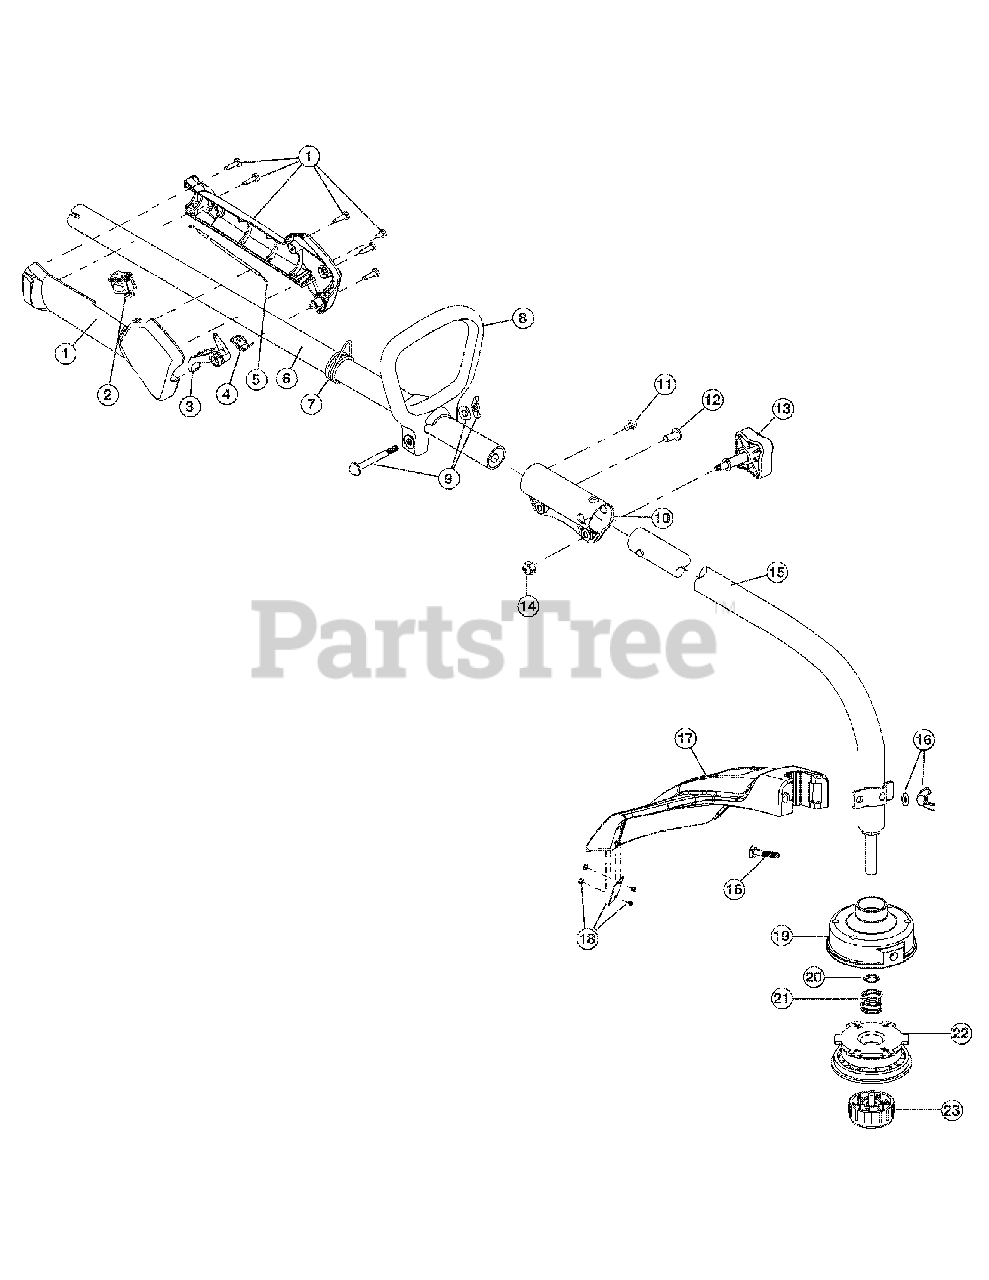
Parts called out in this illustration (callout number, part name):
1	Throttle Housing Assembly (includes 2-4)
3	Throttle Trigger
4	Throttle Trigger Spring
5	Throttle Cable
6	Upper Drive Shaft Housing Assembly
7	Harness Clip
8	D-Handle (includes 9)
9	Handle Hardware
10	Split Boom Coupler (includes 11-14)
13	Adjustment Knob
14	Knob Retaining Nut
15	Lower Drive Shaft Housing Assembly
16	Guard Mounting Hardware
17	Guard (includes 18)
18	Blade Assembly
19	Outer Spool Assembly (includes 20)
22	Inner Reel
23	Bump Head Knob Assembly
